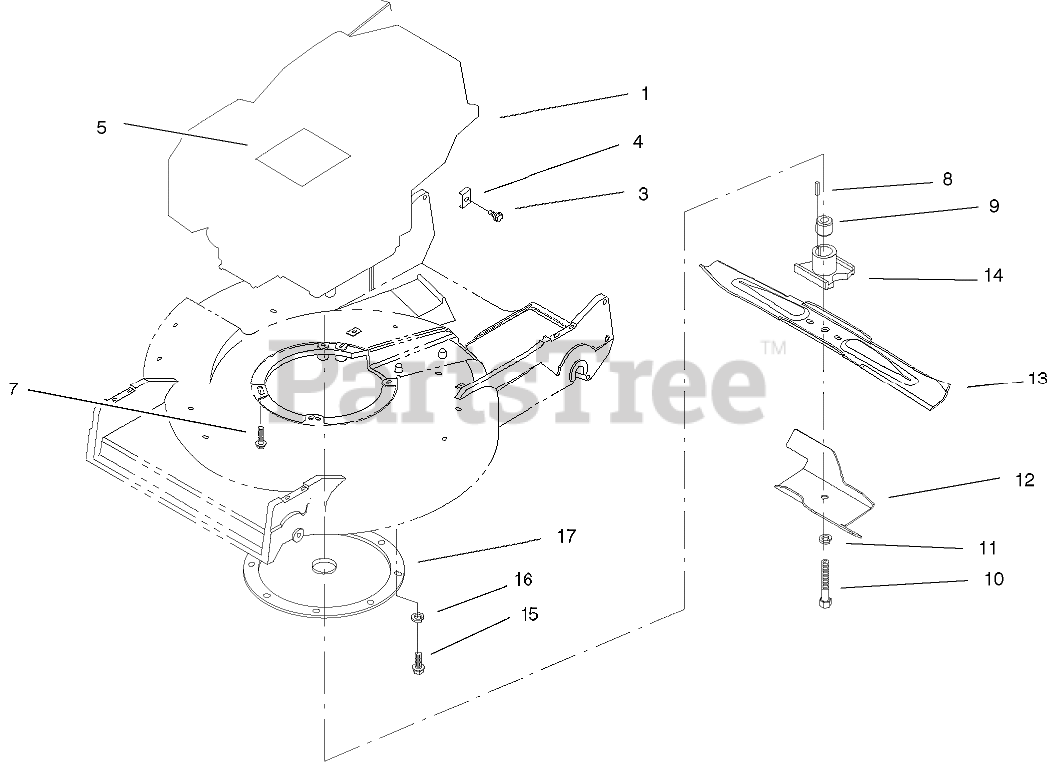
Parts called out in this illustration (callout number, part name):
1	Engine-4cyc Zs, Kawasaki
3	BOLT (5X18)
4	CLAMP
5	Decal-Engine
7	SCREW-MOUNT, ENGINE
8	KEY-SQUARE
9	SPACER-BLADE RETAINER
10	SCREW-BLADE
11	WASHER-LOCK
12	STIFFENER-BLADE
13	Blade
14	Retainer-Blade
15	SCREW-HWHTF
16	WASHER-LOCK, INTERNAL
17	PROTECTOR-CRANKSHAFT
